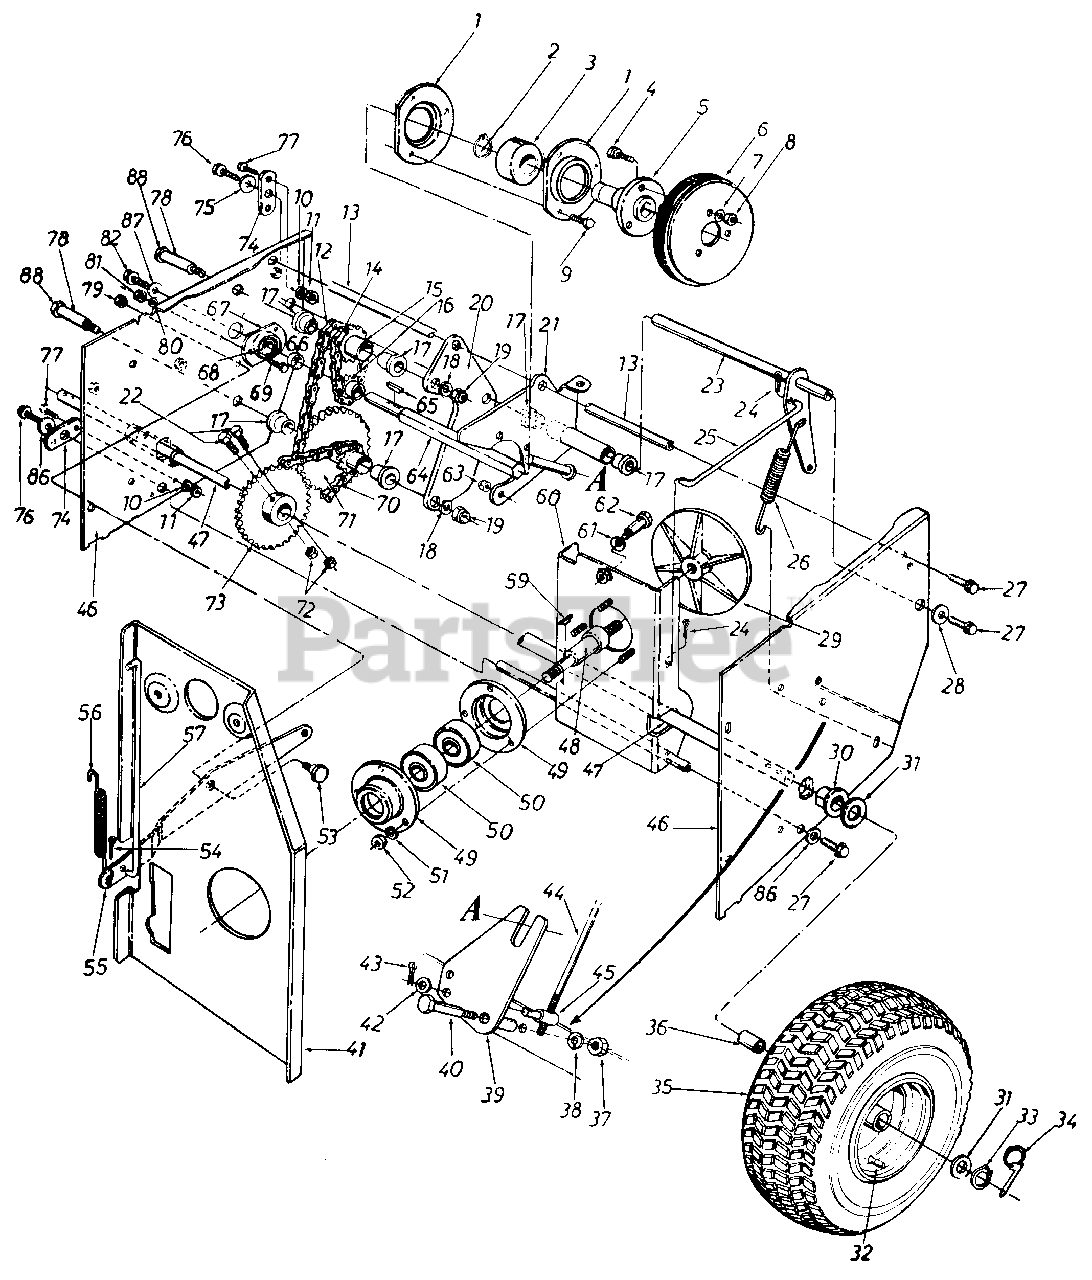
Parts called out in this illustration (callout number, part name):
1	Bearing Housing
2	Snap Ring-1.0" Dia.
3	Ball Brg. .25MM x 52MM x 15MM Thk.
4	Hex Sems Bolt 5/16-18 x .75" Lg. *
5	Friction Wheel Adapter
6	Friction Wheel Ass'y.
7	L-Wash. 5/16" I.D.
8	Hex Nut 5/16-18 Thd.
9	Hex Bolt 1/4-28 x .62" Lg.
10	L-Wash. 1/4" I.D.
11	Hex Nut 1/4-20 Thd.*
12	#41 Chain-1/2" Pitch x 43 Links
12	Master Link (Service Only)
13	Sliding Support Axle
14	#41 Chain-1/2" Pitch x 19 Links
14	Master Link (Service Only)
15	9 and 14 Teeth Sprocket Hub Ass'y.
16	8 Teeth Sprocket
17	Flange Bearing .63" I.D.
18	L-Wash. 318" I.D.-H.D.
19	Hex L-Jam Nut 3/8-24 Thd.
22	Hex Bolt 5/16-24 x 1.75" Lg.
23	Drive Clutch Brkt. Ass'y.
24	Inter. Cot. Pin 5/16" Dia.*
25	Drive Clutch Rod .31" Dia. x 7.38" Lg.
26	Extension Spring 4.31" Lg.
27	Hex L-Bolt 5/16-18 x .62"
28	Fl-Wash. .345" I.D. x .75" O.D.
29	Aluminum Drive Plate
30	Flange Brg. w/Flats
31	Thrust Washer 1.03" I.D.
32	Tubeless Air Valve
33	Snap Ring 1.0" Shaft
34	Klick Pin
35	Wheel Ass'y. Comp. 16 x 4.8
35	Rim Only
36	Bearing 1.0" I.D.
37	Hex Jam Nut 3/8-16 Thd.
38	L-Wash. 3/8" I.D.*
41	Engine Brkt. Ass'y.
42	Fl-Wash. .344" I.D. x .62" O.D.
43	Cotter Pin 3/32" Dia. x .75" Lg.
44	Shifting Rod
45	Adjustment Ferrule
46	Frame Ass'y.
47	Free Wheeling Axle
48	Drive Plate Spindle
49	Bearing Housing
50	Ball Brg. .787" I.D. x 1.85" O.D.
51	L-Wash. 5/16" I.D.
52	Hex Nut 5/16-18 Thd.*
53	Shld. Bolt .625" Dia. x .170" Lg.
54	Inter. Cotter Pin 5/16" Dia.
55	Auger Clutch Brkt.
56	Extension Spring .38" O.D. x 3.18" Lg.
57	Auger Clutch Rod .31" Dia. x 10.62" Lg.
59	#61 Hi-Pro Key 3/16" x 5/8" Dia.
62	Shld. Bolt
63	Hex Ins. Jam Nut 1/4-28 Thd.
64	Hex Shaft
65	#9 Hi-Pro Key 3/32" x 5/8" Dia.
66	Spacer .51" I.D. x .69" O.D.
67	Bearing Housing
68	Ball Bearing
69	Hex Bolt 1/4-20 x .62" Lg.*
70	#420 Chain .50" Pitch x 37 Links
70	Master Link
71	9 and 32 Teeth Sprocket Hub Ass'y.
72	Hex L-Nut 5/16-24 Thd.
73	28 Teeth Sprocket Hub Ass'y.
74	Pivot Axle Brkt.
75	Fl-Wash. .345" I.D. x .75"
76	Hex L-Bolt 5/16-18 x .62"
77	Hex Bolt 1/4-20 x .62n Lg.*
78	Sprocket Hub Tubing 1.88"
79	Hex Cent. L-Nut 3/8-16 Thd.
80	L-Wash. 1/4" I.D
81	Hex Nut 1/4-20 Thd.*
82	Hex L-Bolt 5/16-18 x .62"
86	Fl-Wash. .344" I.D. x .875"
87	Bell-Wash. 345" l.D. x .88"
88	Hex Bolt 3/8-24 x 2.75" Lg.
